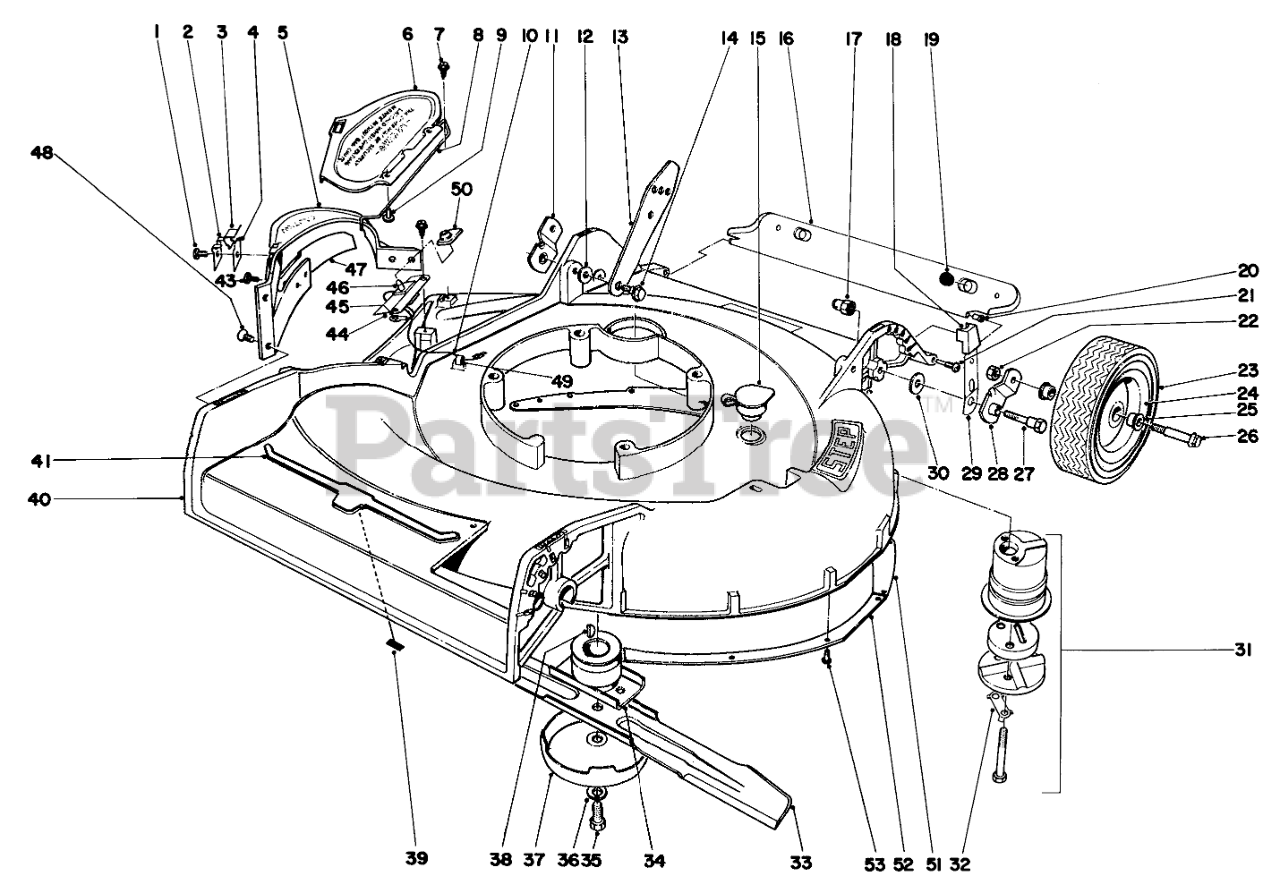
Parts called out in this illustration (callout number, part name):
2	Lower Clip
3	Upper Clip
4	Wear Plate
5	Deflector
6	Deflector (Incl.Ref. #8 & #9)
7	SCREW-HWHTF
8	Hinge Pin
9	Rivet
10	Lead Wire
11	Pivot Arm
12	SPACER
13	Handle Latch
14	SCREW-SHOULDER
15	WASHOUT PLUG
16	Safety Shield(Incl. #19 & #20)
17	Nut
18	Knob
19	SKID BUTTON
20	SAFTEY SHIELD BUSHING
21	SAFTEY SHIELD SCREW
22	Nut
23	8 TIRE
24	Wheel (Incl. Ref. 25)
25	FLANGE BUSHING
27	5/16-18 PIVOT SCREW
28	Pivot Arm
29	Spring Arm
30	Washer
31	Muffler Assy. (Incl. Ref. 32)
32	CLIP - LOCKING
33	Blade
34	BLADE RETAINER WA
35	SPECIAL SCREW
36	WASHER-LOCK
37	AntiScalp Cup
38	KEY-WOODRUFF
40	Housing (Incl. Ref. #51-53)
41	Emblem, Bullshead
44	Mounting Plate
45	Ground Wire
46	Switch
47	DefIector Bar
48	Screw
50	Boot Switch
51	Main Skirt
52	Secondary Skirt
